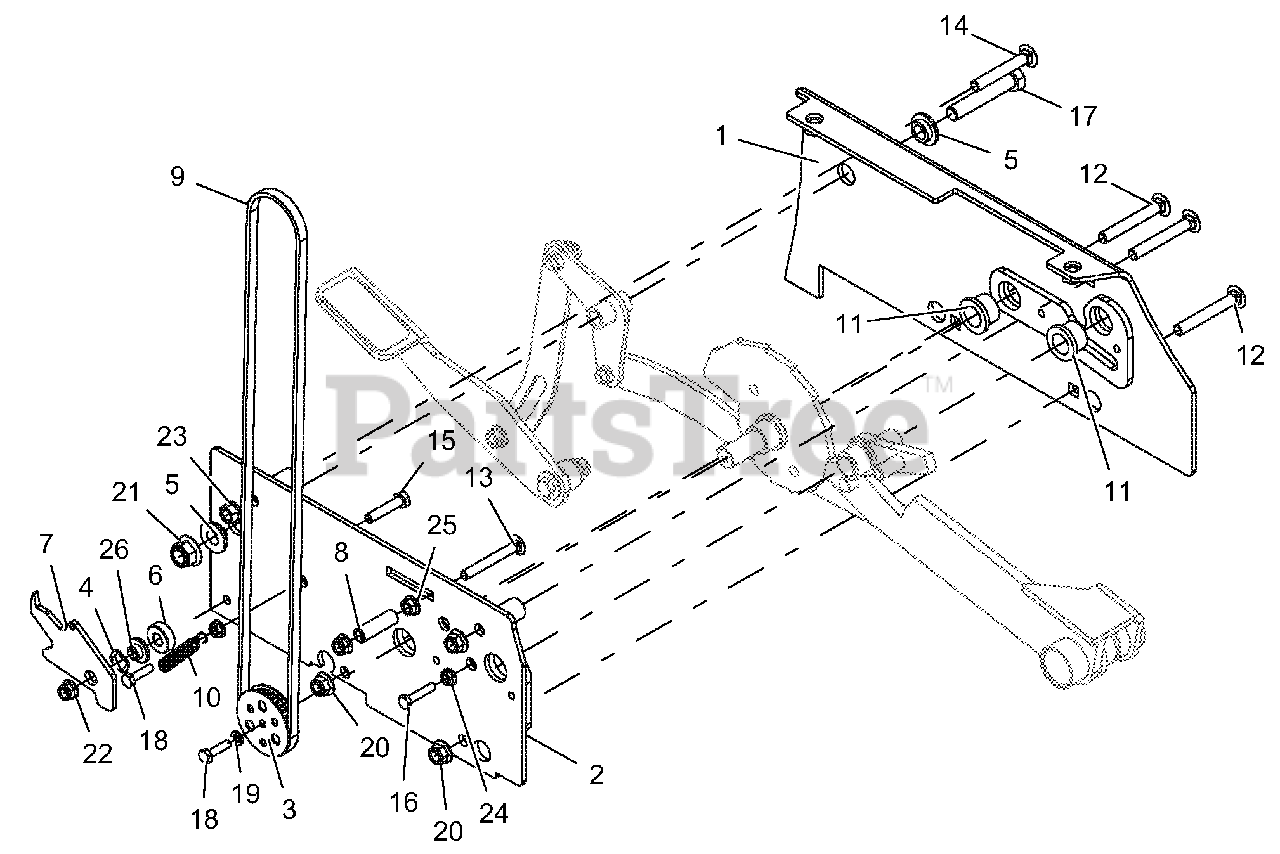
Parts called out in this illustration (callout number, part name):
1	WLDMT, LH BOTTOM TOWER SIDE - RED
2	WLDMT, CAM COVER - RED
3	WLDMT, PULLEY
4	WAVE WASHER .531 x .781 x .125 FH
5	BSHG, FLANGE .515 x .750 x .31x 1.12
6	SPCR, .375 x 1.00 x .342
7	LATCH, FOOT PEDAL
8	BSHG, SLV .33 x .50 x 1.56
9	BELT, TIMING - LONG
10	SPRG, EXTENSION
11	BUSHING, .750 x 1.00 x .750
12	BLT-RDHDSQNK .38-16 x 2.75 G5 Y
13	BLT-RDHDSQNK .31-18 x 2.50 G5 Y
14	BLT-RDHDSQNK .38-16 x 2.50 G5 Y
15	BLT-HEX .31-18 x 1.50 GR5 YWZC
16	BLT-HEX .25-20 x 1.25 GR5 YWZC
17	BLT-HEX .50-13 x 2.75 GR5 YWZC
18	BLT-HEX .25-20 x 1.00 GR5 YWZC
19	WSHR-LK .25 x .062 REG YWZC
20	NUT-LK-NYL-FLG .38-16 YWZC
21	NUT-LK-NYL-FLG .50-13 YWZC
22	NUT-LK-NYL-FLG .31-18 YWZC
23	NUT, LK-TOP-FLG .38-16 YWZC
24	@NUT-SPNLK-FLG .25-20 YWZC
25	@NUT-SPNLK-FLG .312-18 YWZC
26	BSHG, FLG .32 x .500. 344 x .880
